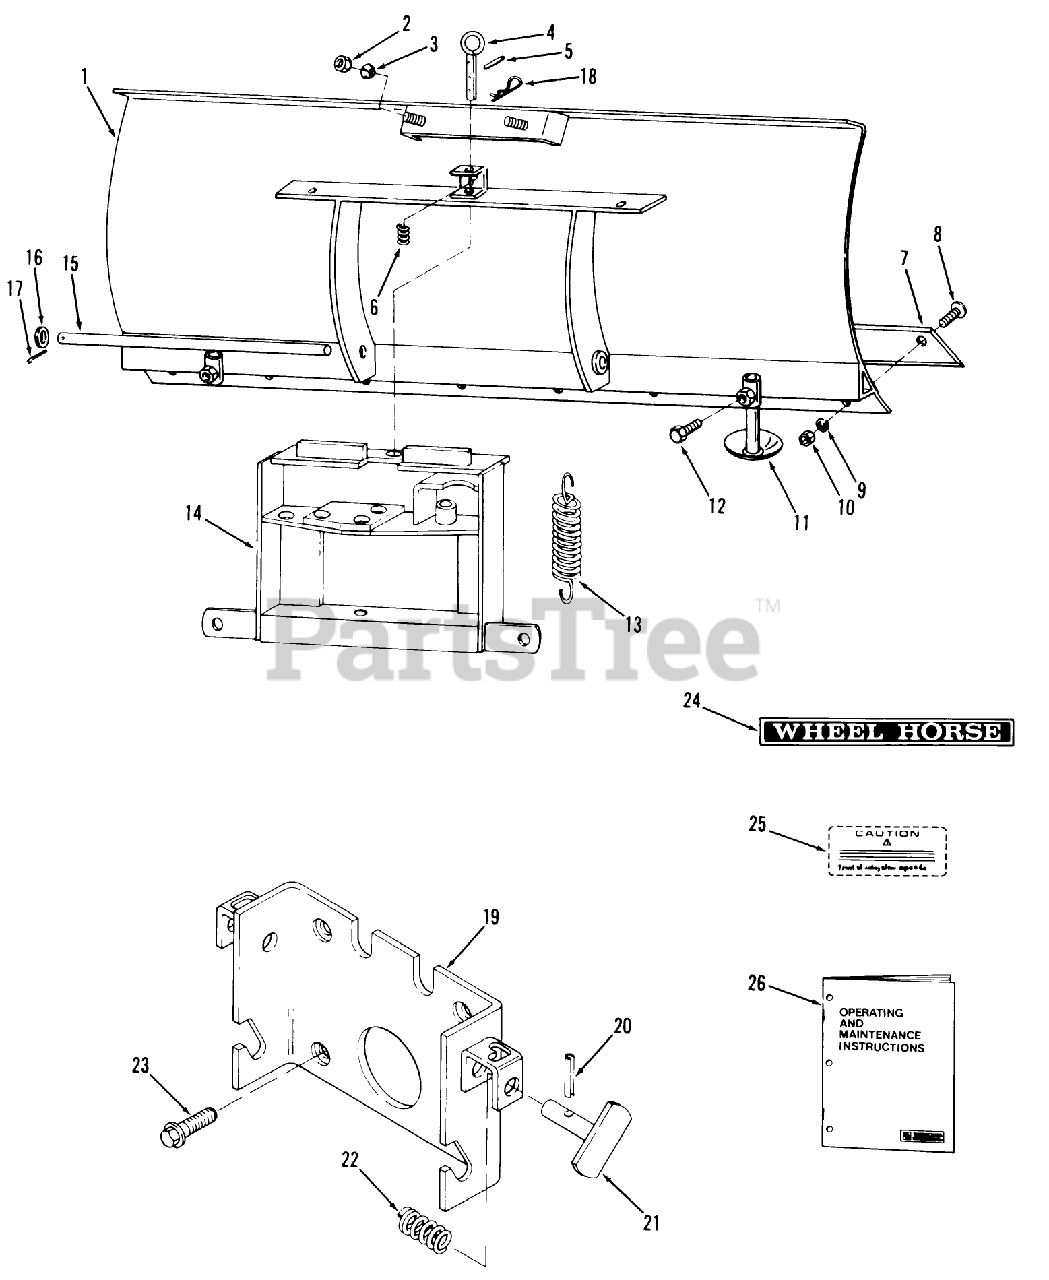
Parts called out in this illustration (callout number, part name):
1	Blade
3	Spring Lockasher
14	Indexing Bracket
15	Mounting Rod
19	Mounting Plate
21	Locking Pin
26	MANUAL-OPERATOR
